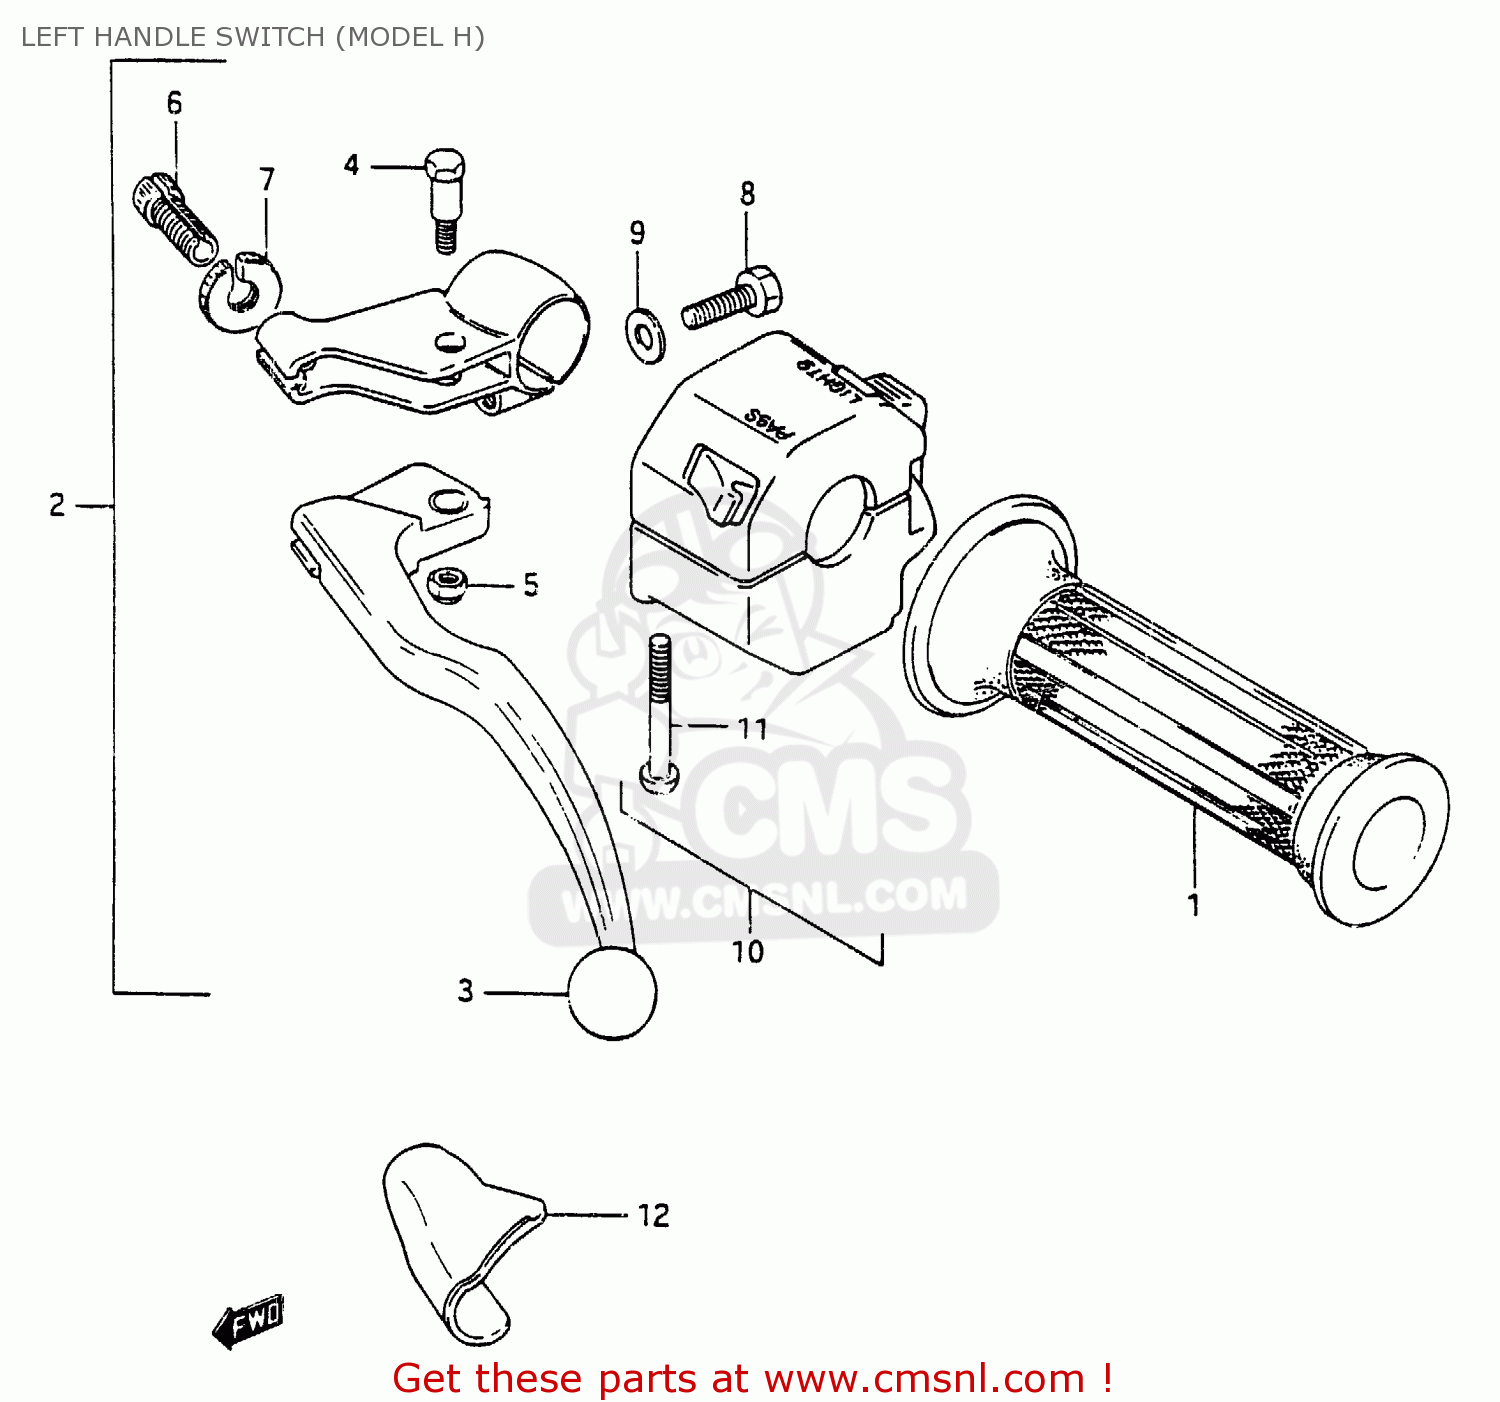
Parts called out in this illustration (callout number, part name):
1	GRIP,L
2	LEVER ASSY, CLUTCH
3	LEVER,CLUTCH
4	BOLT,LEVER PIVOT
5	NUT
6	ADJUSTER,CABLE
7	NUT,CABLE ADJUSTER LOCK
8	BOLT
9	WASHER
10	SWITCH ASSY, HANDLE LH
11	SCREW
12	COVER,CLUTCH LEVER
